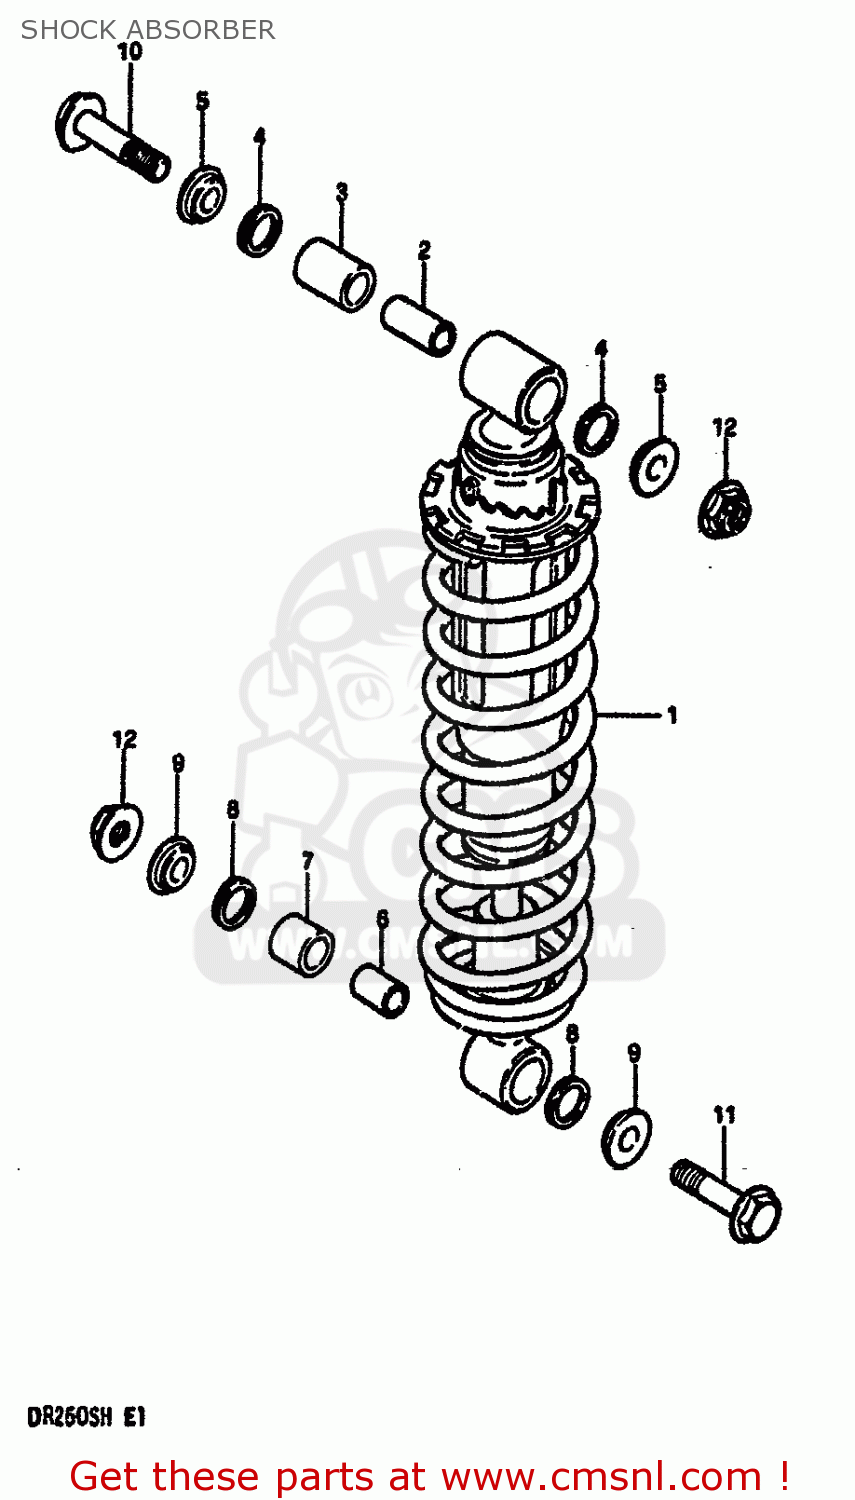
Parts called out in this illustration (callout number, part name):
1	SHOCK ABSORBER,REAR (BLUE)
2	BUSH
3	BUSHING,REAR SHOCK,UPPER
4	O-RING,FORK INNER TUBE
5	COLLAR
6	BUSHING,REAR SHOCK ABSORBER
7	BUSHING,REAR SHOCK,LOWER
8	O-RING,FORK INNER TUBE
9	COLLAR
10	BOLT(10X60)
11	BOLT(10X50)
12	NUT
